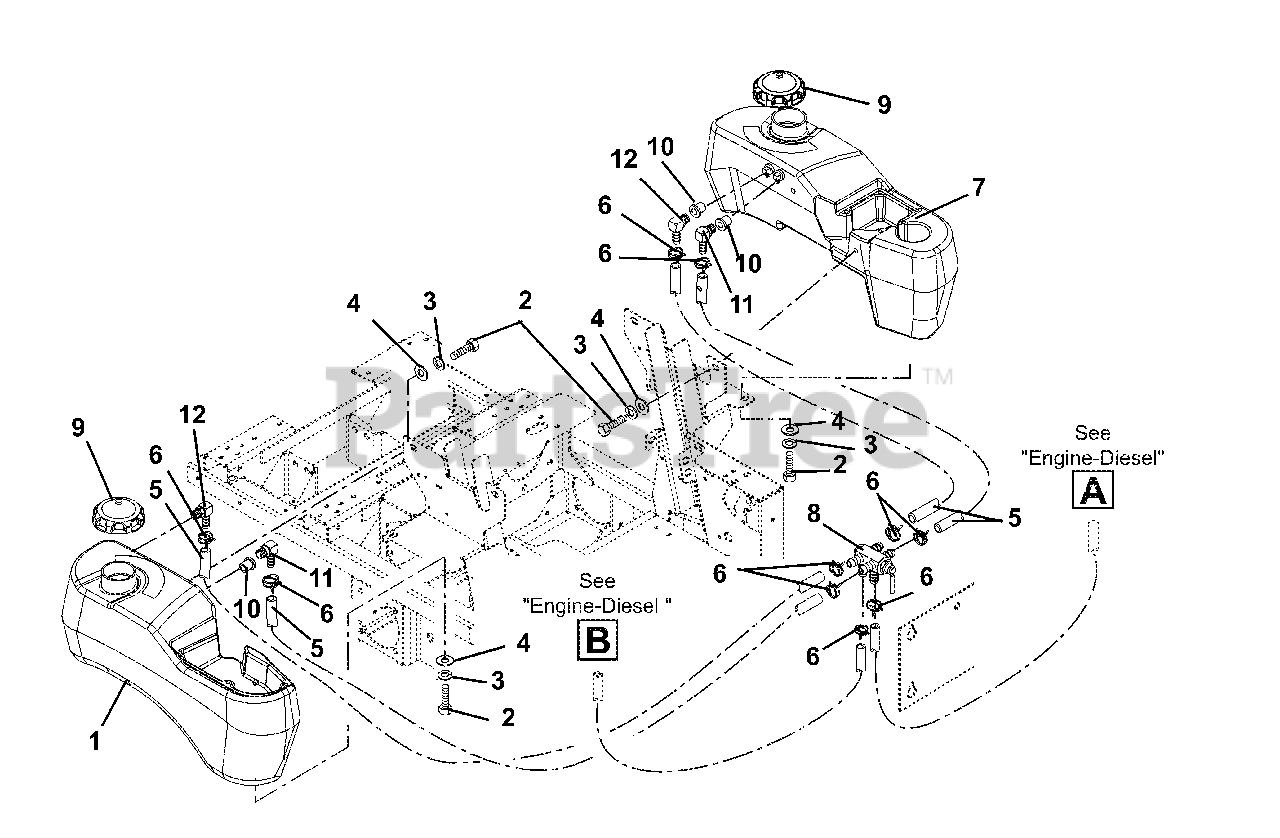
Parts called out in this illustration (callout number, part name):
1	Tank, Fuel-Right Hand (075, 076, 318, 319)
2	Bolt, Hex .31-18 x .75 Grade 5
3	Washer, Locking .31 x .078
4	Washer, Flat Steel .38 x .875 x .083
5	Hose, .31 ID (075, 076, 318, 319)
6	Clamp, Hose Wire .52/.55 (075, 076, 318, 319)
7	Tank, Left Hand Fuel (EYE-Q) 200 Series-EFI (075, 076, 318, 319)
8	Valve, Fuel (075, 076, 318, 319)
9	Cap, Fuel (075, 076, 318, 319)
11	Fitting, Tank (075, 076, 318, 319)
12	Fitting, Tank (075, 076, 318, 319)
